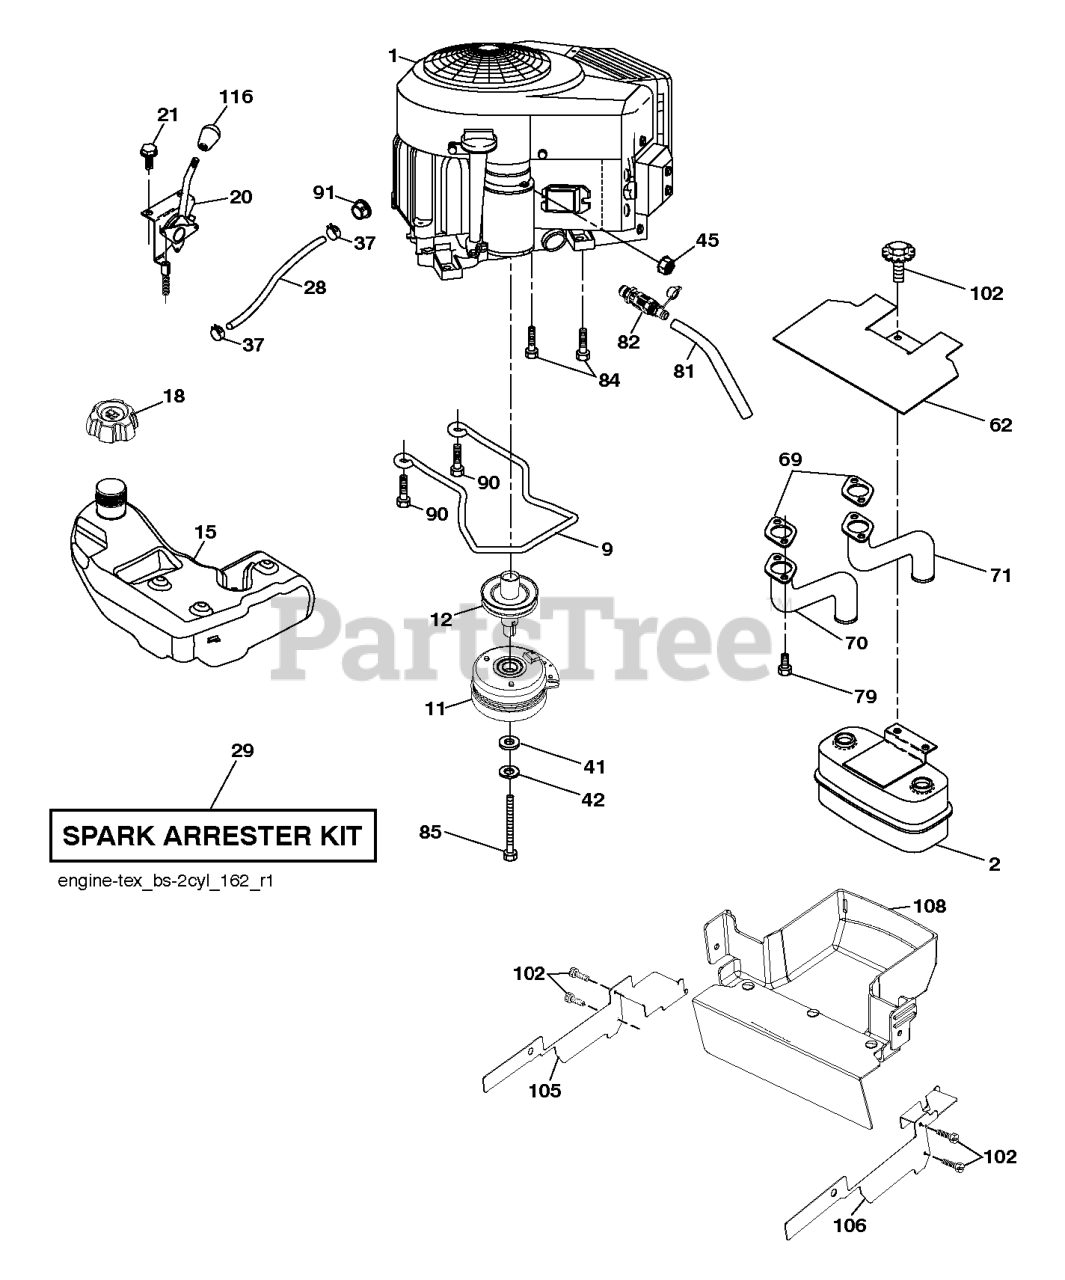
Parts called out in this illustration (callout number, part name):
2	MUFFLER.ASM.TWIN.MNTG.BRACKET
11	CLUTCH. 5.0 PD. 2.5 OFFSET
12	PULLEY.EXTENDED.SHAFT.GROUND
15	TANK.FUEL.4GAL
18	CAP.ASSY.FUEL.3".N-EPA.GRY.498
20	CONTROL.THROTTLE.PRO.
28	LINE.FUEL.64"REAR.EMIS
29	KIT.SPARK ARRESTOR 794945 B&S
37	HOSE CLAMP
62	SHIELD.HEAT.MUFFLER
69	GASKET.MUFFLER
70	EXHAUST.TUBE.LH.BS/TWIN
71	EXHAUST.TUBE.RH.B&S.TWIN.INTEK
81	TUBE, DRAIN OIL ASM.
82	VALUE.OIL.DRAIN
84	SCREW.3/8-16
85	BOLT.HEX.7/16-20X5.GR5.GREEN
90	SCREW 3/8-16X1
91	BUSHING.1.375OD
102	SCREW
105	SHIELD 48 CLEARCUT EURO TRACTO
106	SHIELD 48 CLEARCUT EURO TRACTO
108	COVER 48 CLEARCUT EURO TRACTOR
116	KNOB - SHIFT
